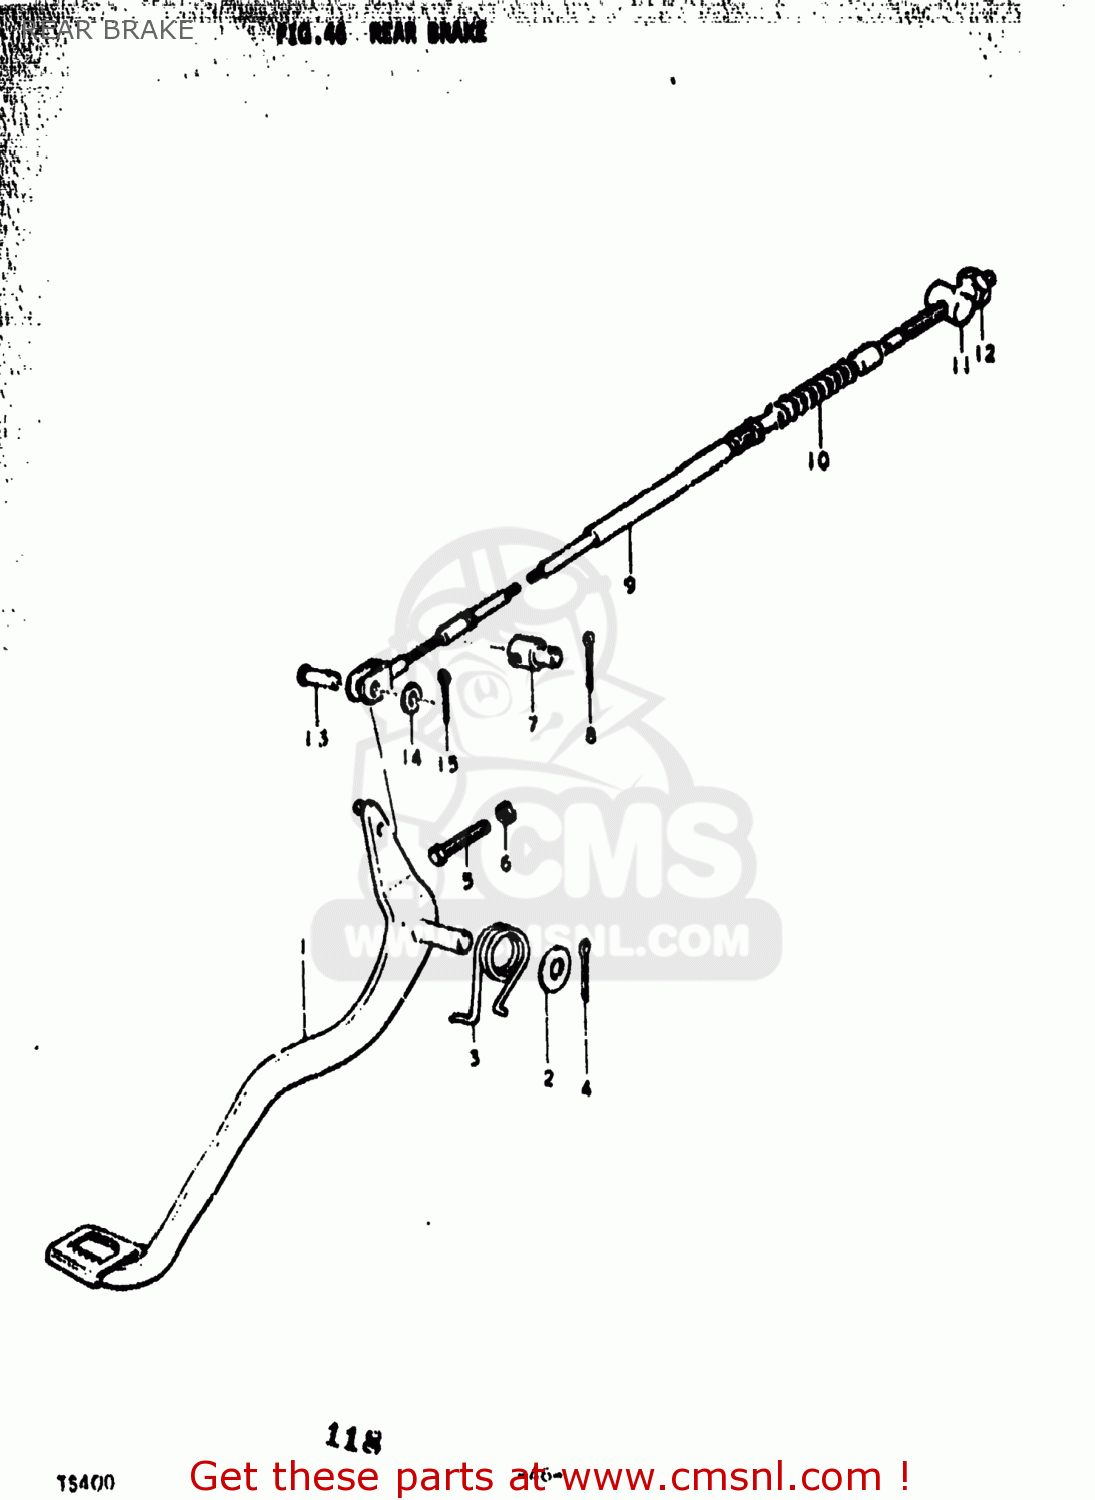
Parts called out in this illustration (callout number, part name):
1	PEDAL,BRAKE
2	WASHER
3	SPRING
4	COTTER PIN
5	BOLT
6	NUT
7	PROP STAND
8	PIN 25X20
9	CABLE,RR BRAKE
10	SEAL,DUST
11	PIN
12	NUT
13	PIN(L:13.5)
14	WASHER
15	PIN
